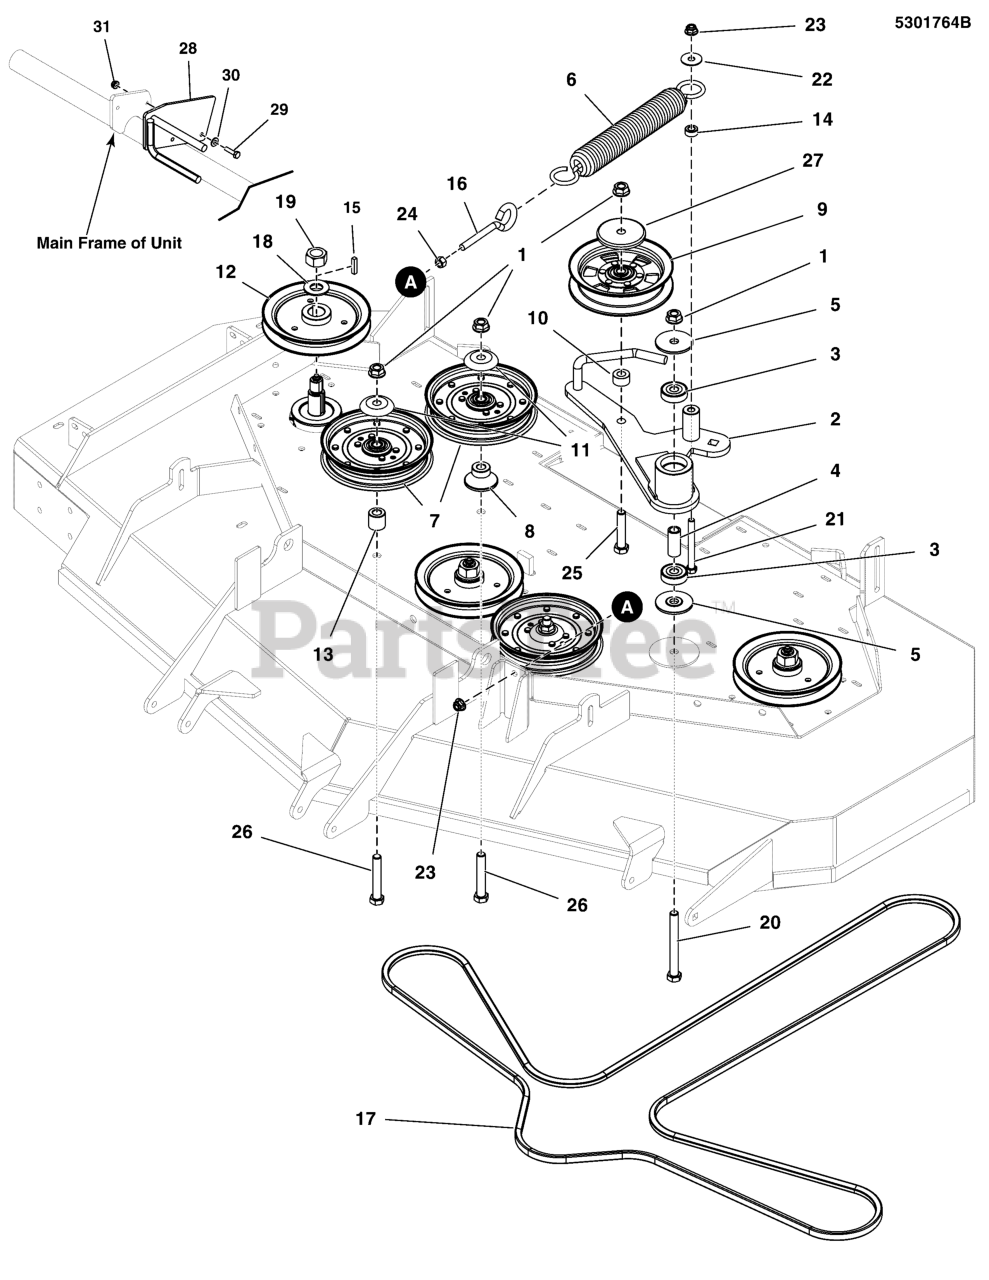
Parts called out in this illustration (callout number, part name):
1	NUT, Hex Flange, Nylock, 1/2-13
3	BEARING, 6203-1/2", SEALED
4	SPACER, .510 X .750 X 1.749, CZ
5	SPACER, IDLER ARM, 1/2 X 2.25
6	SPRING, EXT, 1.5ODX12.25X.234WIRE BLK
8	IDLER MOUNT
9	PULLEY,IDLER,BACKSIDE,NOSEAM 6.25ODX.5ID
10	SPACER, .52 X 1.00 X .56, PM, CZ
11	SHIELD, PULLEY BEARING, CZ
12	PULLEY, 6.702OB X .985ID, SINGLE B-SEC
13	SPACER, .52 X 1.00 X 1.00
14	SPACER, .39 X .75 X .38, PM, CZ
15	KEY, 1/4 SQ X 1-1/4
16	EYE BOLT, 3/8-16 X 5, 2.88THRD, 1EYE, CZ
17	BELT, 5V, 172.75"EL, LG ARAMID WRPD, RC
18	WASHER, 3/4 BELLEVILLE CL/ZC
19	NUT, 3/4-16 HEX
20	BOLT, 1/2-13 X 4-1/2 GD5 CZ
21	BOLT, 3/8-16 X 3-1/2" GD5 CZ
22	WASHER-3/8 FENDER
23	NUT, 3/8-16 HEX NYLOCK FLANGE
24	NUT, 3/8-16 HEX SERRATED FLANGE
25	BOLT, 1/2-13 X 2-1/2" GD5 CZ
26	BOLT, 1/2-13 X 3" GD5 CZ
27	SHIELD, BEARING, 1/2 ID X 2-7/8 OD, CZ
28	WELD, CLUTCH BELT GUIDE - BLK
29	BOLT, 1/4-20 X 1" GD5 CZ
30	WASHER, 1/4 SAE
31	NUT, 1/4-20 HEX NYLOCK FLANGE
